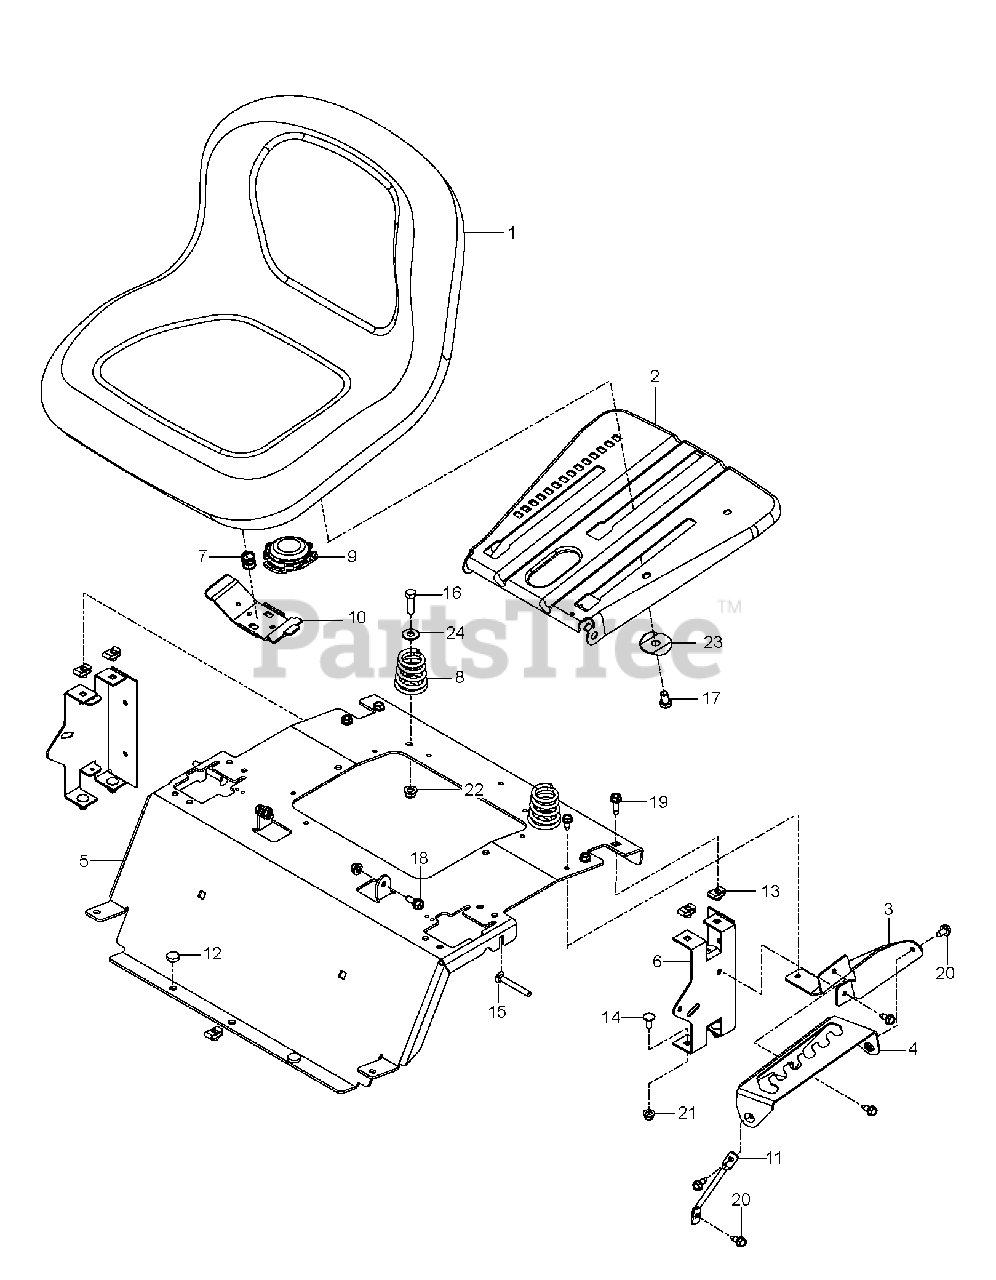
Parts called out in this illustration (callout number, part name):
1	SEAT.TH150.MS498.GRY.HUSQ.TEX
2	Seat Slide Plate, Pnt
3	PLATE.SUPPORT.DECK.LIFT.X431
4	PLATE.DECK.LIFT.X431
5	PLATE.SUPPORT.SEAT.RZ.ORANGE
6	SUPPORT REAR SEAT BLACK
7	SPRING.LATCH.SEAT.TEX
8	SPRING.COMPRESS.SEAT.
9	SWITCH.SEAT.DELTA.OPC.
10	HANDLE.SLIDE.SEAT.TEX.BLACK
11	SUPPORT.LEG.DECK.LIFT
12	GROMMET.BUMPER
13	U-CLIP 5/16-18 NUT RETAINER
14	BOLT 5/16-18 X3/4 ZN/YEL GR 5
15	RHSNB 5/16-18 X 2-1/2 GR5 ZD
16	BOLT
17	HCS 3/8-16 X 5/8 GR 5 ZD
18	BOLT, SHOULDER
19	SCREW
20	BOLT.5/16HEX.WHS.HD
21	5/16-18 NYLOC FLANGE NUT
22	NUT 3/8-16 HEX FLG NYLOC ZD
23	Winged Washer, 38Id 1
24	WASHER 3/8 FLAT
